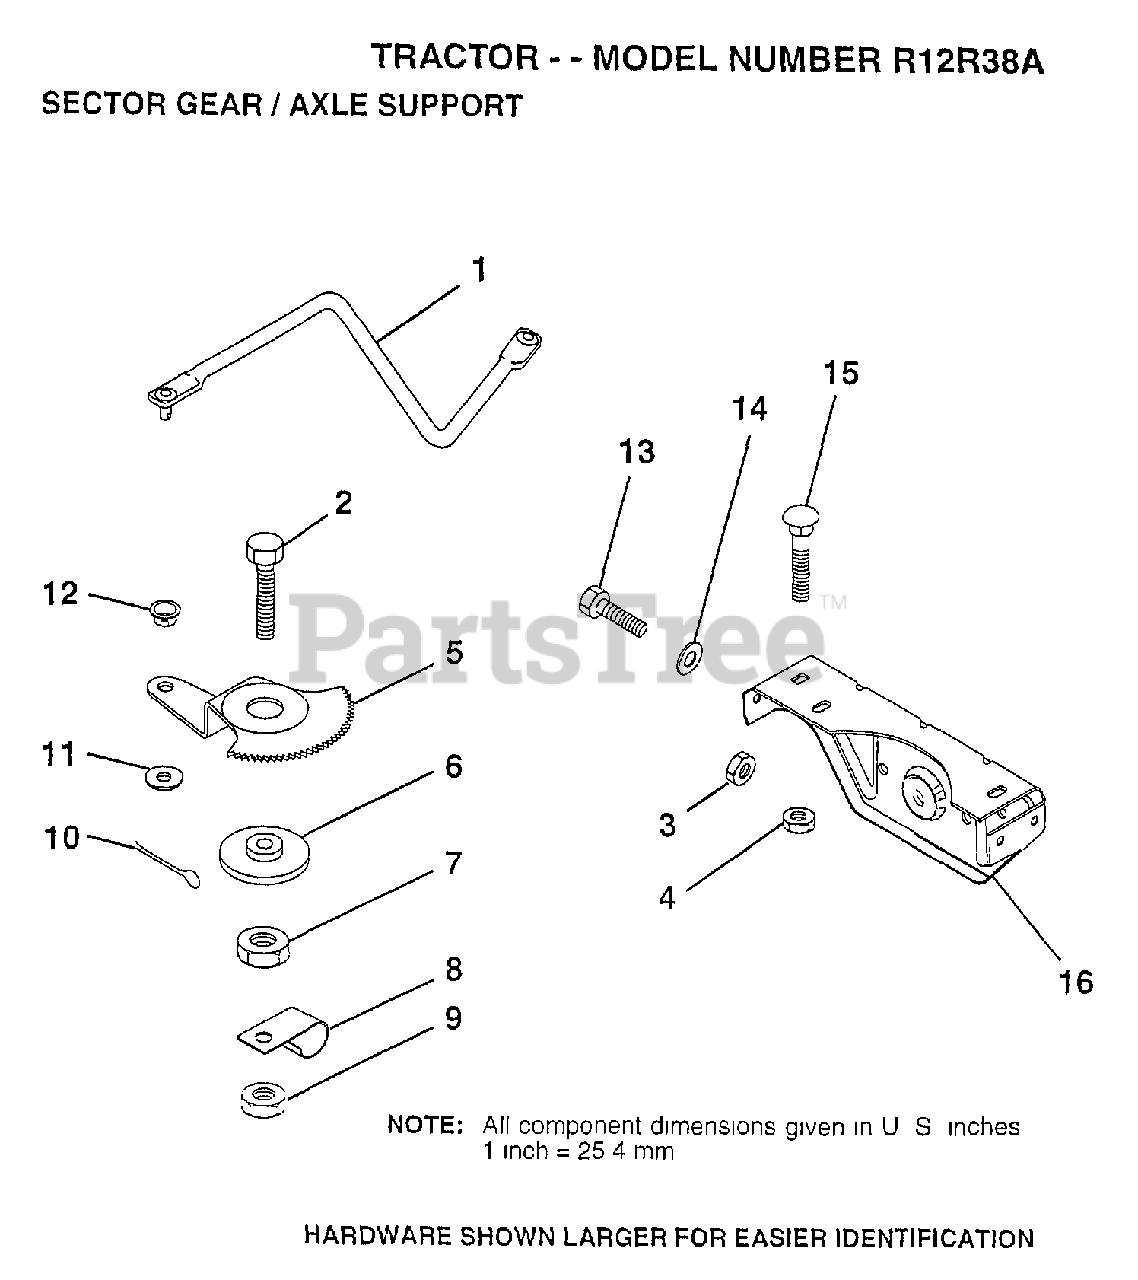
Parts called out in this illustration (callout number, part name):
1	DRAG LINK
2	"BOLT,HEX"
3	NUT
5	GEAR SECTOR
6	BUSHING
7	NUT
8	CLIP INSULATOR
9	NUT LTV
10	COTTER PIN
11	WASHER
12	BUSHING.DRAGLINK
13	BOLT
14	WASHER
15	BOLT
16	SUPT AXLE FRONT
